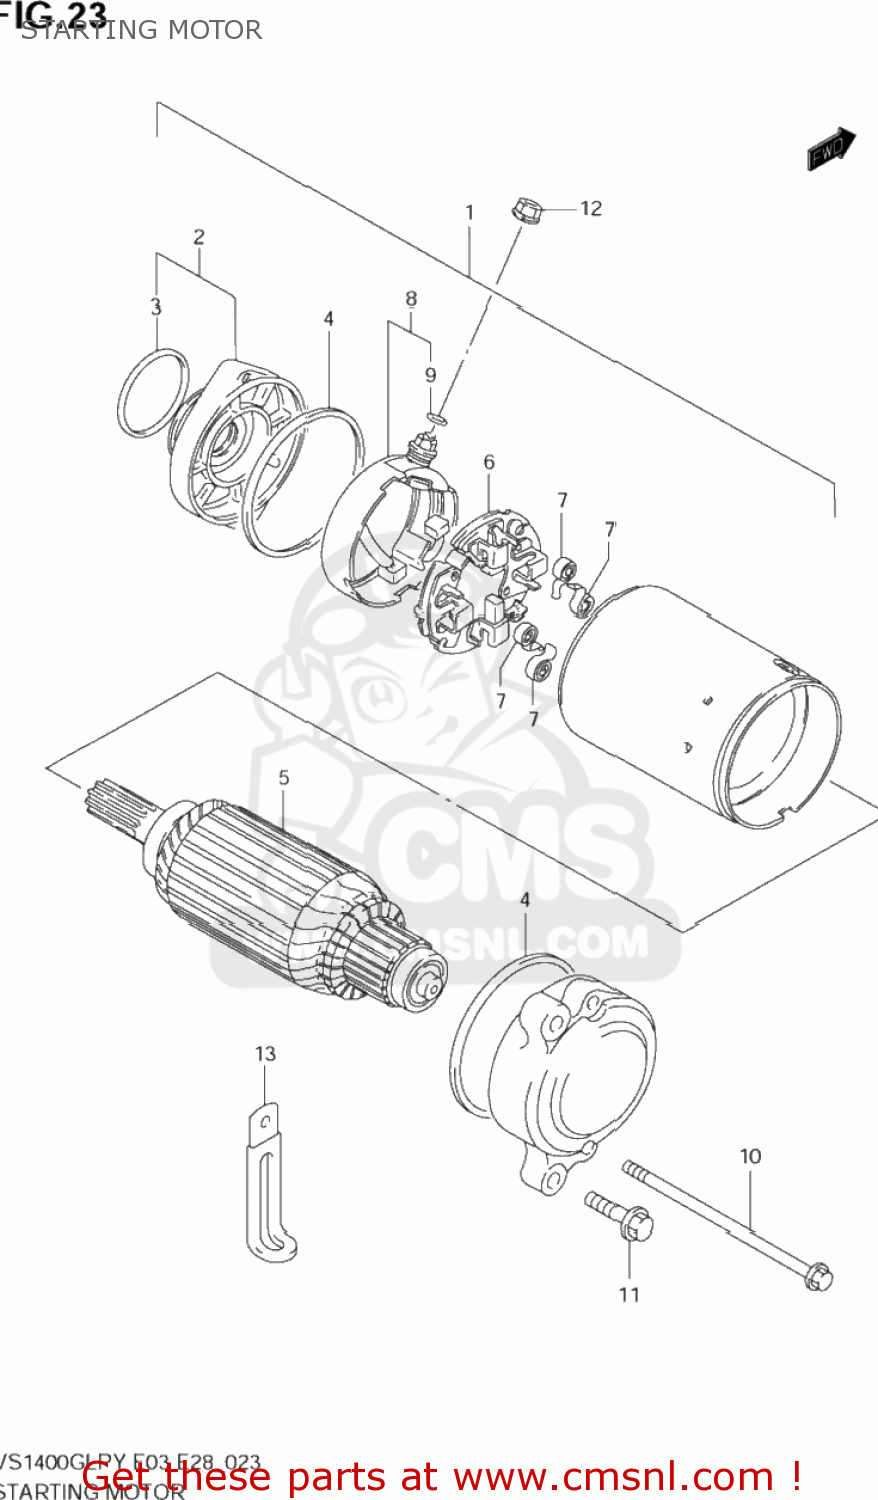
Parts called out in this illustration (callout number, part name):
1	MOTOR ASSY,STARTING
2	BRACKET SET
3	O-RING
4	O RING
5	ARMATURE
6	HOLDER SET,BRUSH
7	SPRING,BRUSH
8	TERMINAL SET,BRUSH
9	O RING
10	BOLT
11	BOLT
12	NUT
13	CLAMP(L:65)
